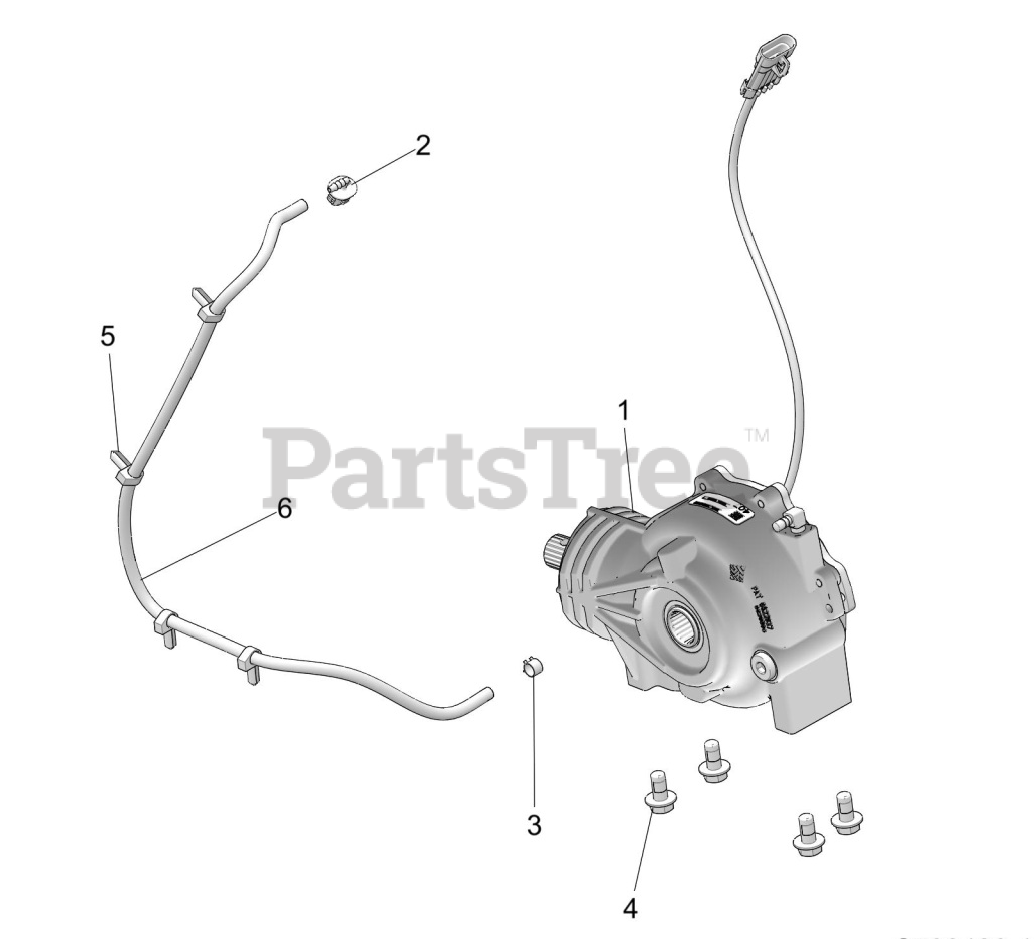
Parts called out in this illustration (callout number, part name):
2	FITTING-VENT LINE,90
3	CLAMP,HOSE(10)
4	BOLT-M10X1.5X20,HXFLG,W/PATCH
6	LINE-BOOST,3/16 ID,76CM
